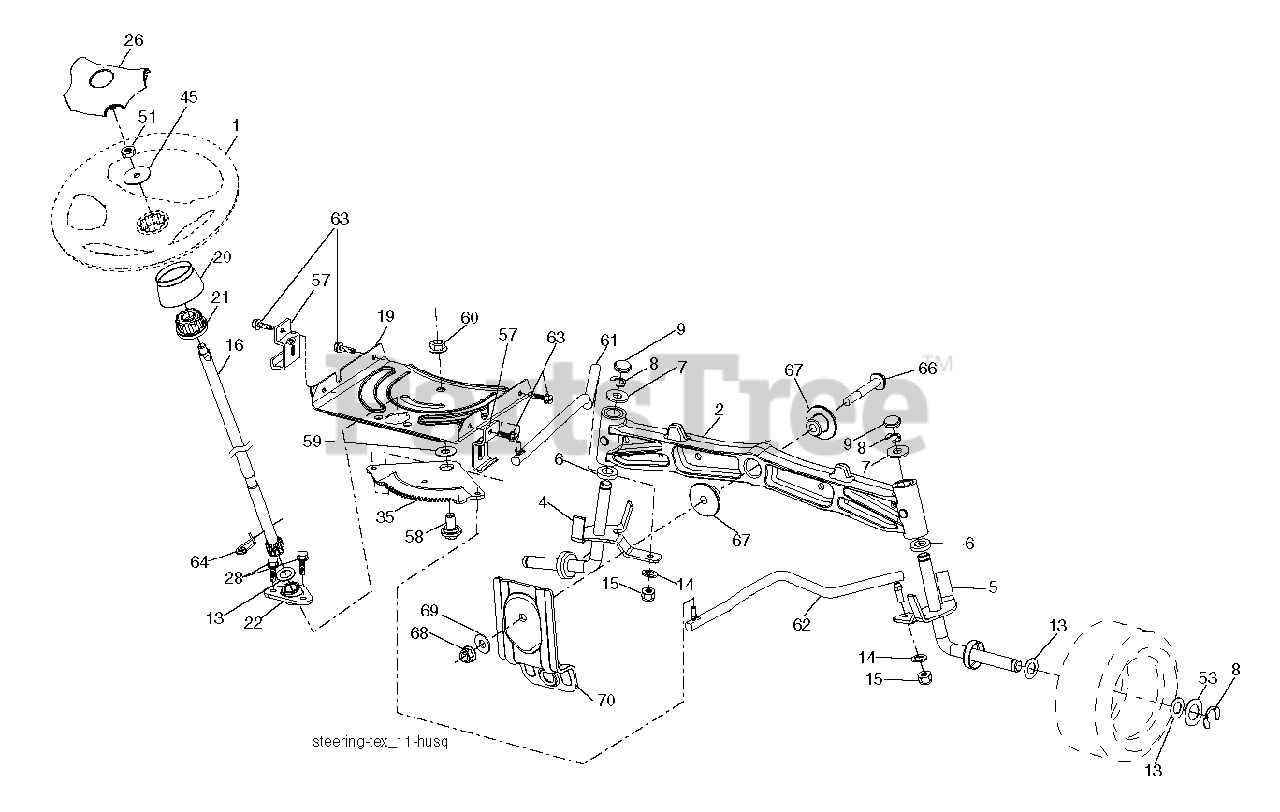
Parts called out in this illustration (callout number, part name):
1	WHEEL.STEERING.PREM.2.BLK
2	AXLE.CAST.IRON
4	SPINDLE.WELDED.LH.15"TEX
5	SPINDLE.WELDED.RH.15"T
8	RING CLIP
9	CAP.SPINDLE
14	WASHER, LOCK 3/8
15	NUT CROWNLOCK 3/8-24
16	SHAFT.STEER.STEALTH.DD
19	PLATE.STEER.DDL.NLT/NG
20	BOOT.STEERING.
21	ADAPTER, WHEEL STNG..
22	BUSHING.ASM.STEERING.A
26	INSERT.CAP.STRG.WH.GRAY
28	SCREW, 3/8-16X3/4
35	GEAR.SECTOR.PLATE.DDL.
45	WASHER 9/16"ID, 2 3/8"OD
51	NUT.HEX.1/2-20
53	WASHER.HARDENED
57	BRACKET.UPSTOP.TEX
58	BOLT.SHOULDER.SECTOR.P
59	WASHER.THURST.SECTOR.S
60	NUT FLANGE LOCK 5/8-11
61	DRAGLINK.LH.BALLSTUD.D
62	DRAGLINK.RH.BALLSTUD.D
63	SCREW
64	RETAINER.CLIP.SPRING.S
66	BOLT HEX FGHD 7/16-14 X 3 SERR
67	BUSHING.PM.FRONT AXLE
68	NUT.LOCK.FLANGE.7/16
69	WASHER.1.5X.505X.118
70	BRKT.DECK.SUSPENSION.F
